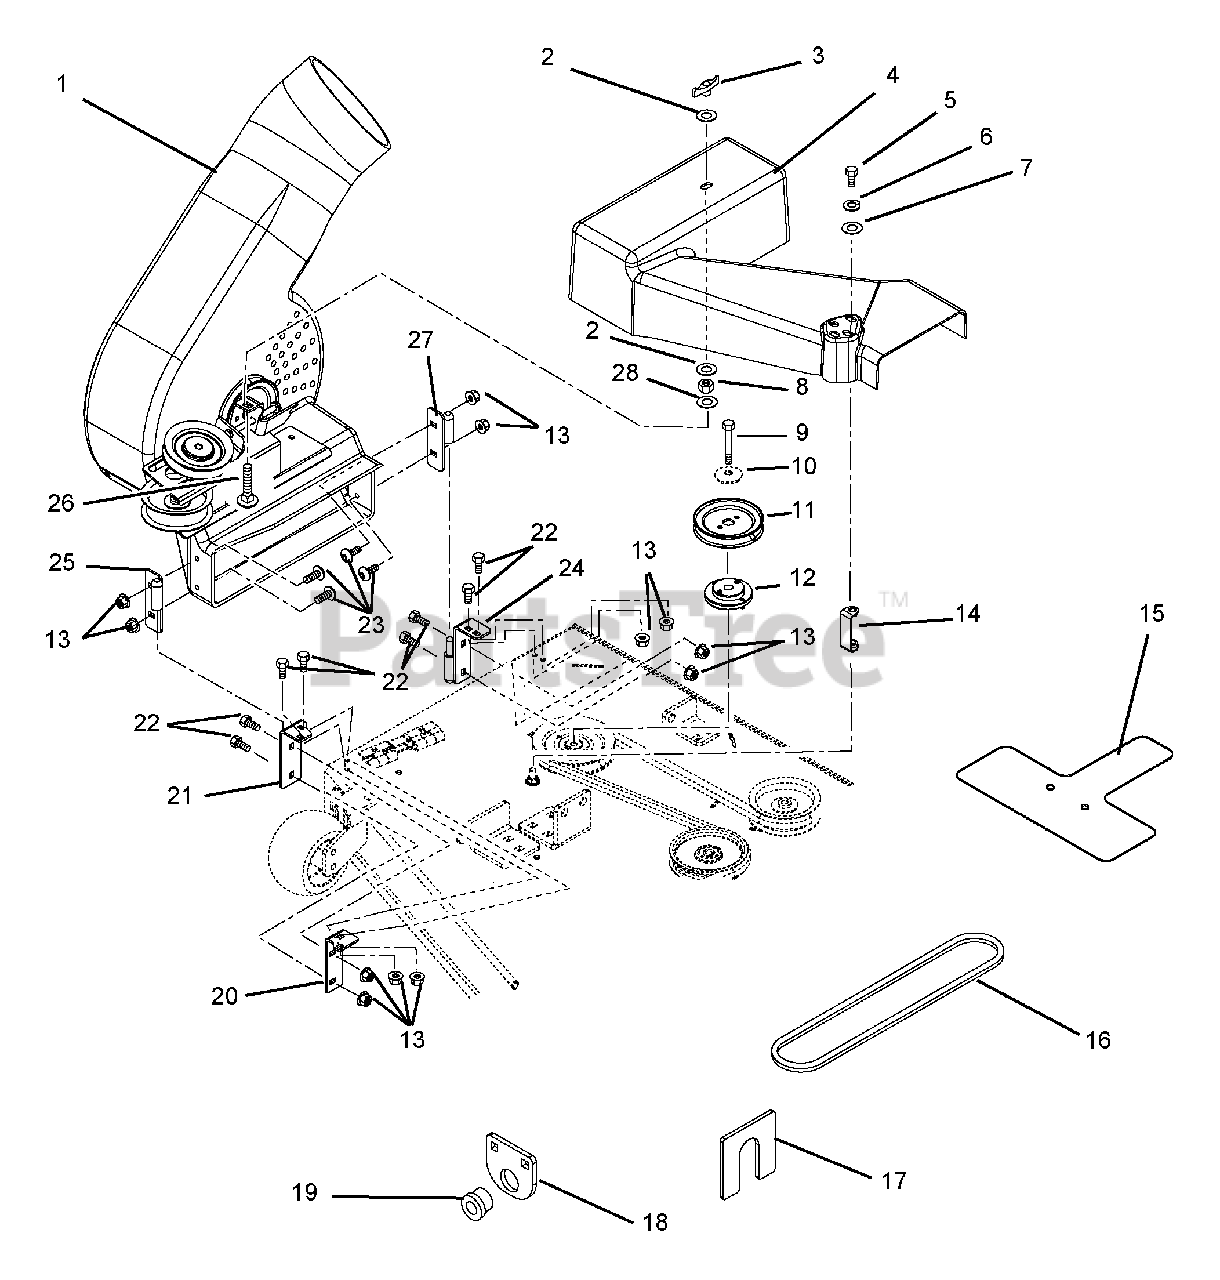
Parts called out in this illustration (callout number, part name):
1	BLOWER HSG W/DECAL
2	WSHR-FL-STL .380X1.50X.062 YWZ
3	KNOB - WING .312-18 UNC
4	BELT COVER W/DECAL
5	@BLT-HEX .38-16X.75 GR5 YWZC
6	@WSHR-LK .38X.094 REG YWZC
7	@WSHR-FL-STL.438X1.00X.083 YWZ
8	NUT- JAM .312-18 YWZC
9	BLT-HEX .38-16X1.75 GR8 M-EPYZ
10	WASHER, CUPPED SERRATED, .375
11	SHEAVE, 3.00 DIA.
11	SHEAVE, 4.00 DIA.
12	ASSEMBLY, SHEAVE ADAPTER
13	@NUT-LK-TOP-FLG .25-20 YWZC
14	SPACER, COVER
15	GUARD,FINGER
16	V-BELT, HA-WRAPPED
16	V-BELT, HA-RAW EDGE
17	PLATE,LIFT
18	BRACKET,REAR PIVOT
19	BSHG-FLG 1.000X1.12X.62X1.50BR
20	BRACKET, FRONT
21	WELDMENT, FRONT MOUNT BRACKET
22	@BLT-HEX .25-20X.75 GR5 YWZC
23	SCR-MCH .25-20X.75 TXTR YWZC
24	WELDMENT, REAR MOUNT BRACKET
25	WELDMENT, HOUSING MOUNT RH
26	@BLT-RDHDSQNK .31-18X1.50 G5YZ
27	WELDMENT, HOUSING MOUNT LH
28	@WSHR-FL-STL.312X.734X.065 YWZ
